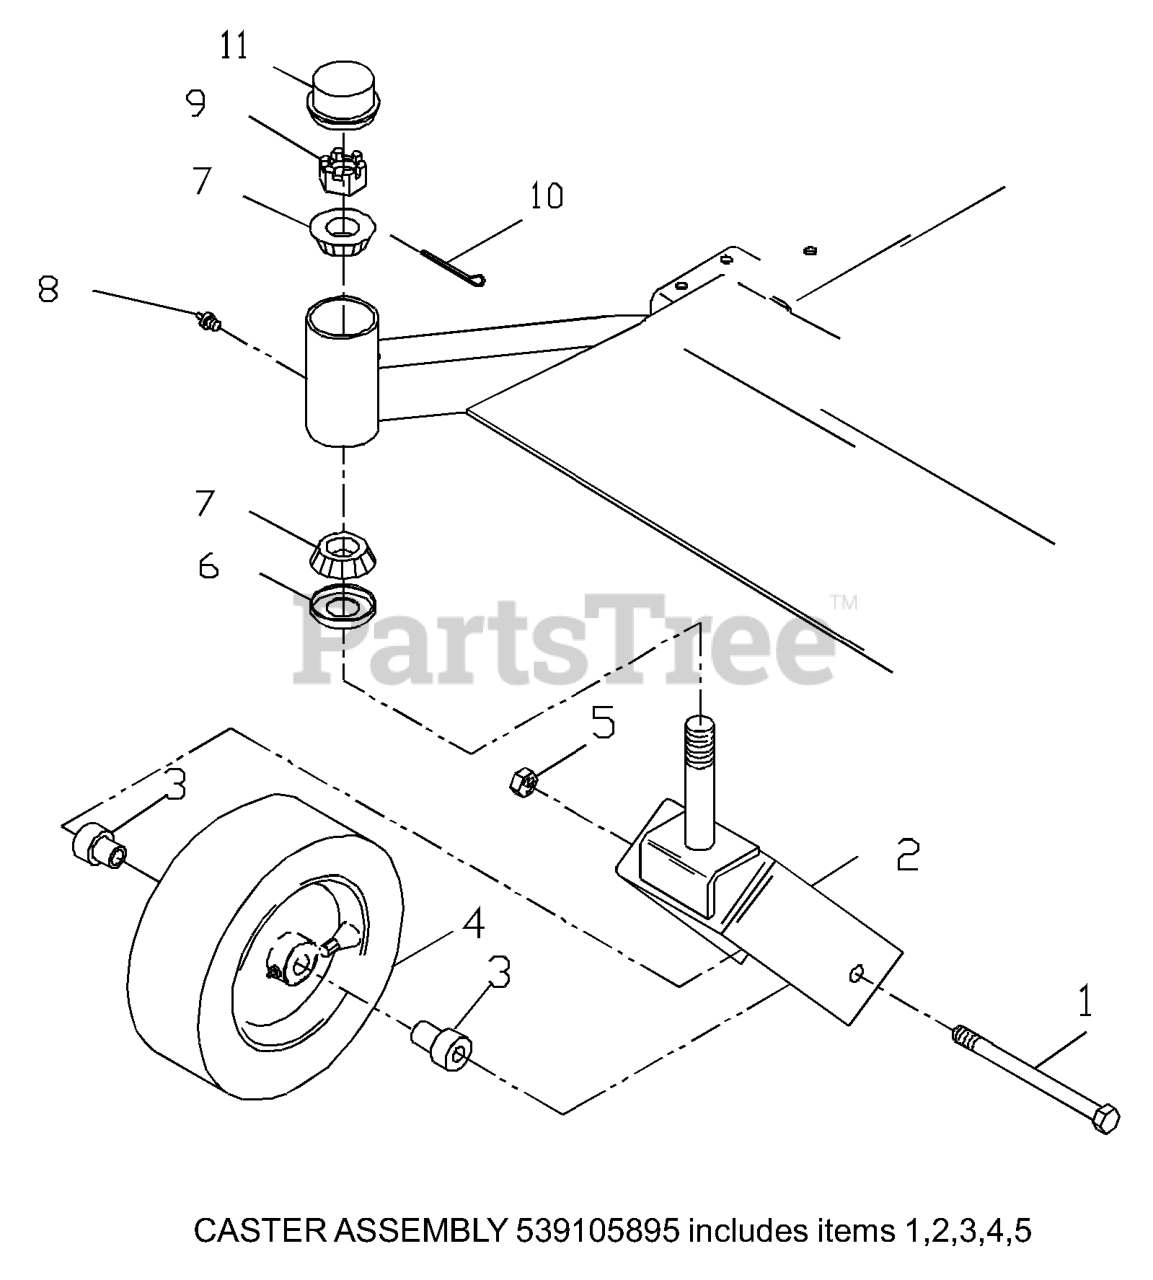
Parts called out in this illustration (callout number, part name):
1	HEX SCREW 1/2-13 X 9.5 GR5
2	CASTOR YOKE ORANGE
3	AXLE SPACER
4	FRONT TIRE ASSY
4	TIRE - SMOOTH 13X6.50-6
4	TAPERED BEARING W/RACE
4	VALVE STEM TR-412
5	NUT 1/2-13 HEX NYLOC ZD
7	BEARING W/CUP
8	ZERK
9	COTTER PIN 1/8 X 2
10	NUT 1"C HEX SLOTTED
11	GREASE CAP
539105895	XP CASTOR ASSY
